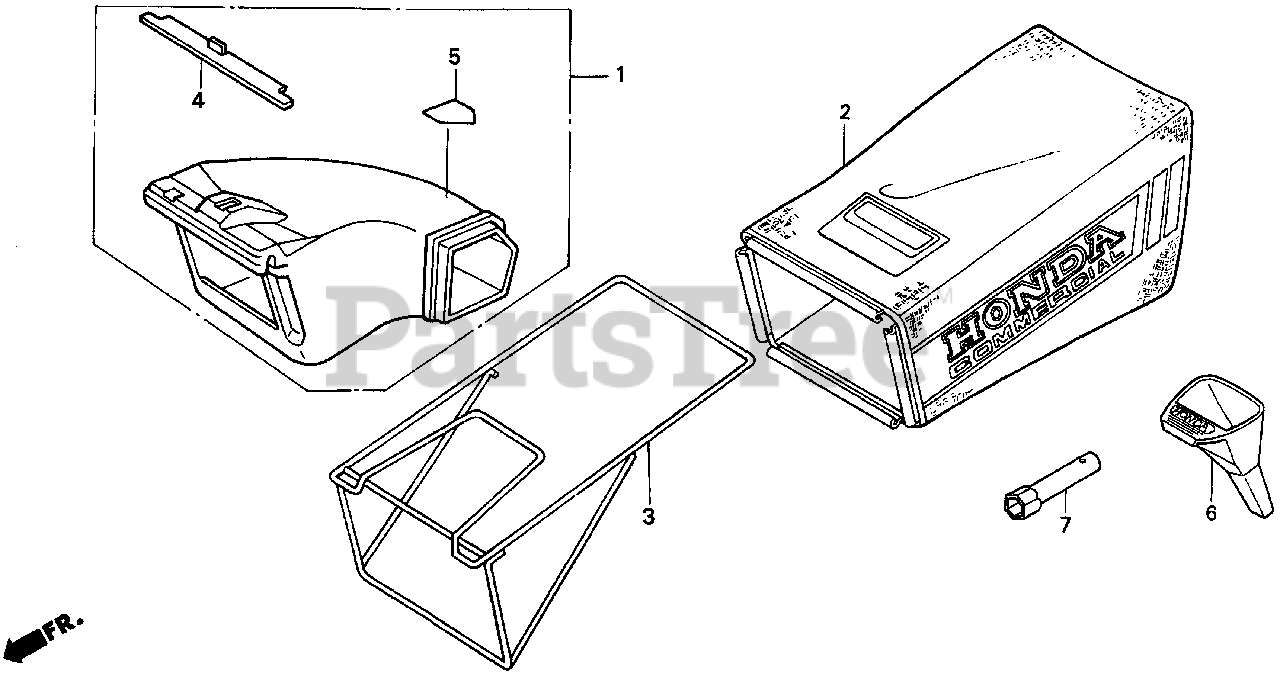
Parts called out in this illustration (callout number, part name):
1	CHUTE KIT, SIDE DISCHARGE
2	FABRIC, GRASS BAG
3	FRAME, BAG
4	BRACKET, MOUNTING (NOT AVAILABLE)
5	CAUTION C, HOUSING
6	FUNNEL, OIL
7	WRENCH, BOX (P21)
